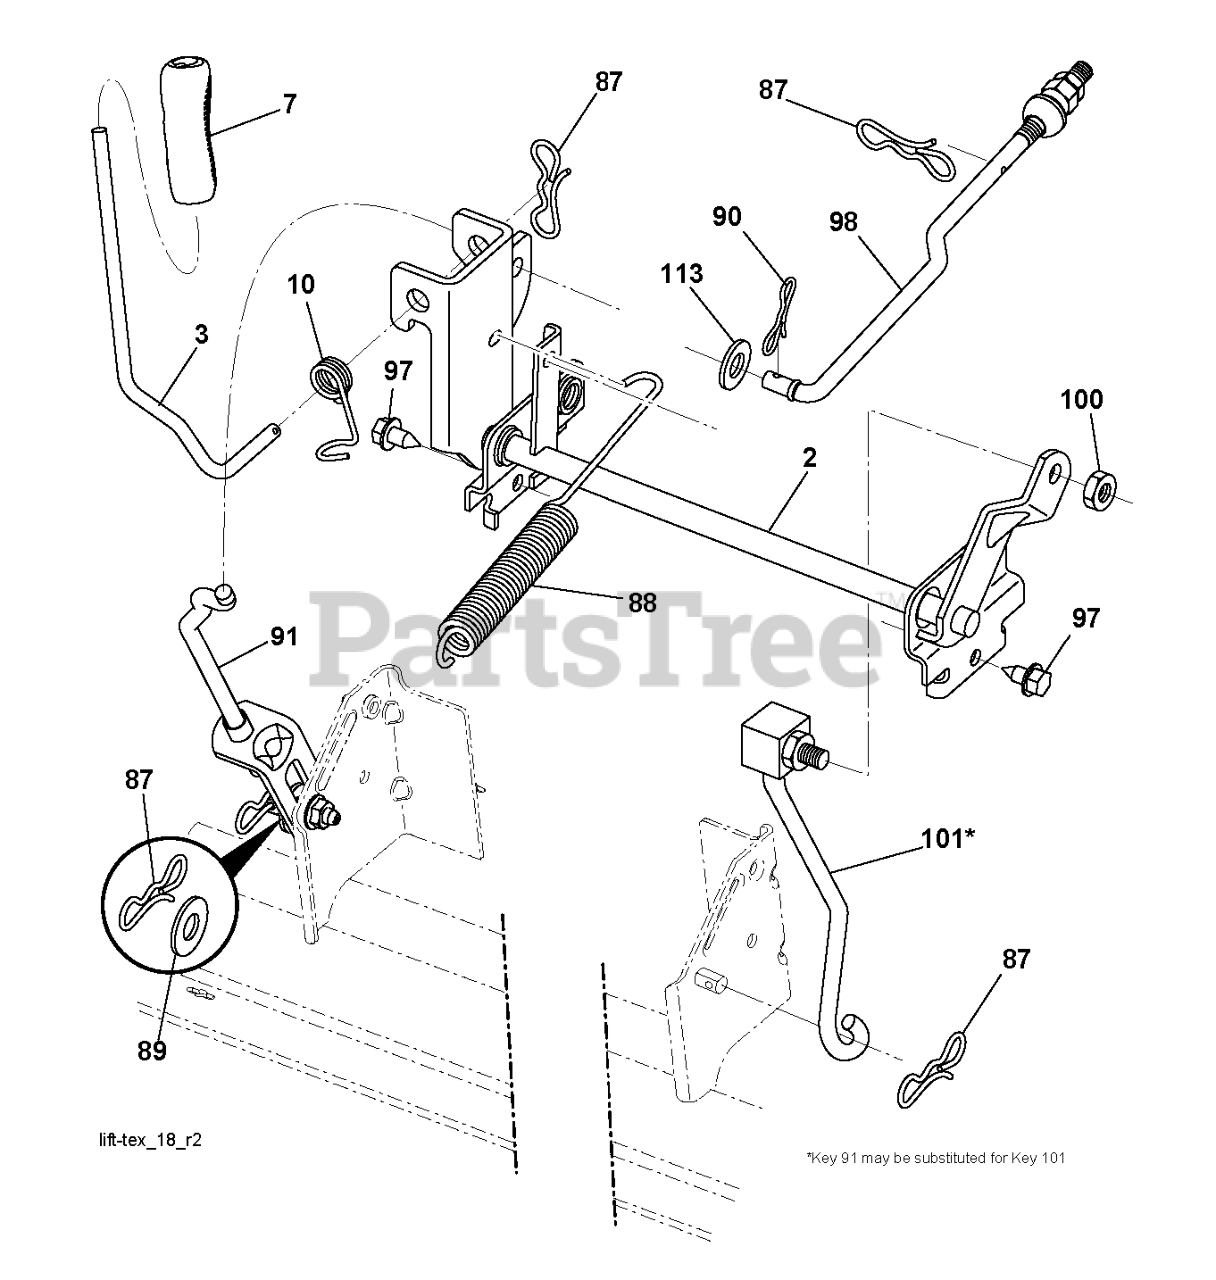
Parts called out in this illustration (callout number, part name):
2	SHAFT.ASM.CROSS.LIFT
3	LEVER.LIFT.HANDLE.LT
7	GRIP.HANDLE.LIFT.PVC.BLACK
10	SPRING.TORSION.LIFT.HANDLE
87	PIN.COTTER.7/16.BOW TI.
88	SPRING.LIFT.ASSIST
89	WASHER.CLEAR.ZINC
90	PIN.COTTER.5/16.BOW TI
91	LINK.ASM.LIFT.REAR
97	SCREW, 3/8-16X3/4
98	LINK.ASM.SUSP.FRONT.MWR.10.5
100	LOCKNUT
101	LINK.ASM.LIFT.FIXE.38/42/46"
